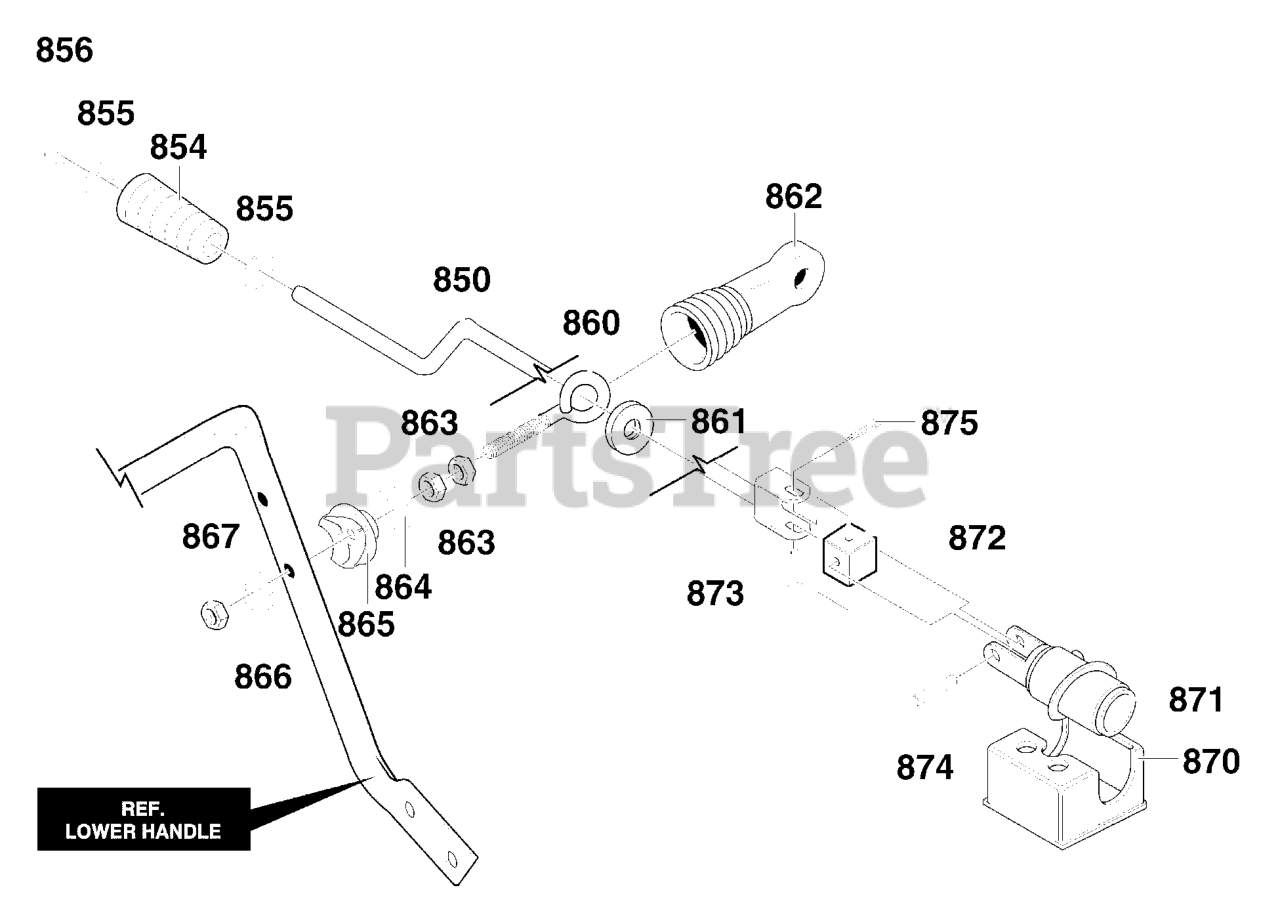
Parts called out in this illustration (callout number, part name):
850	CRANK, ASSY
855	WASHER, FLAT .406X .81X.066
856	RING, RETAINER
860	BOLT, EYE 3/8-16X6.00
861	GROMMET, EYE BOLT
862	BOOT
863	NUT, 3/8-16 HEXJAM
864	WASHER, FLAT .406X .81X.066
865	ADAPTOR, BOOT TO HANDLE
866	WASHER, FLAT .406X .81X.066
867	NUT, 3/8-16 HEXNYL
870	BRKT, WORM
871	WORM, GEAR CHUTE
872	BLOCK, UNIV PIV
873	PIN, CLEVIS
874	PIN, UNIV JOINT
875	PIN, COTTER
